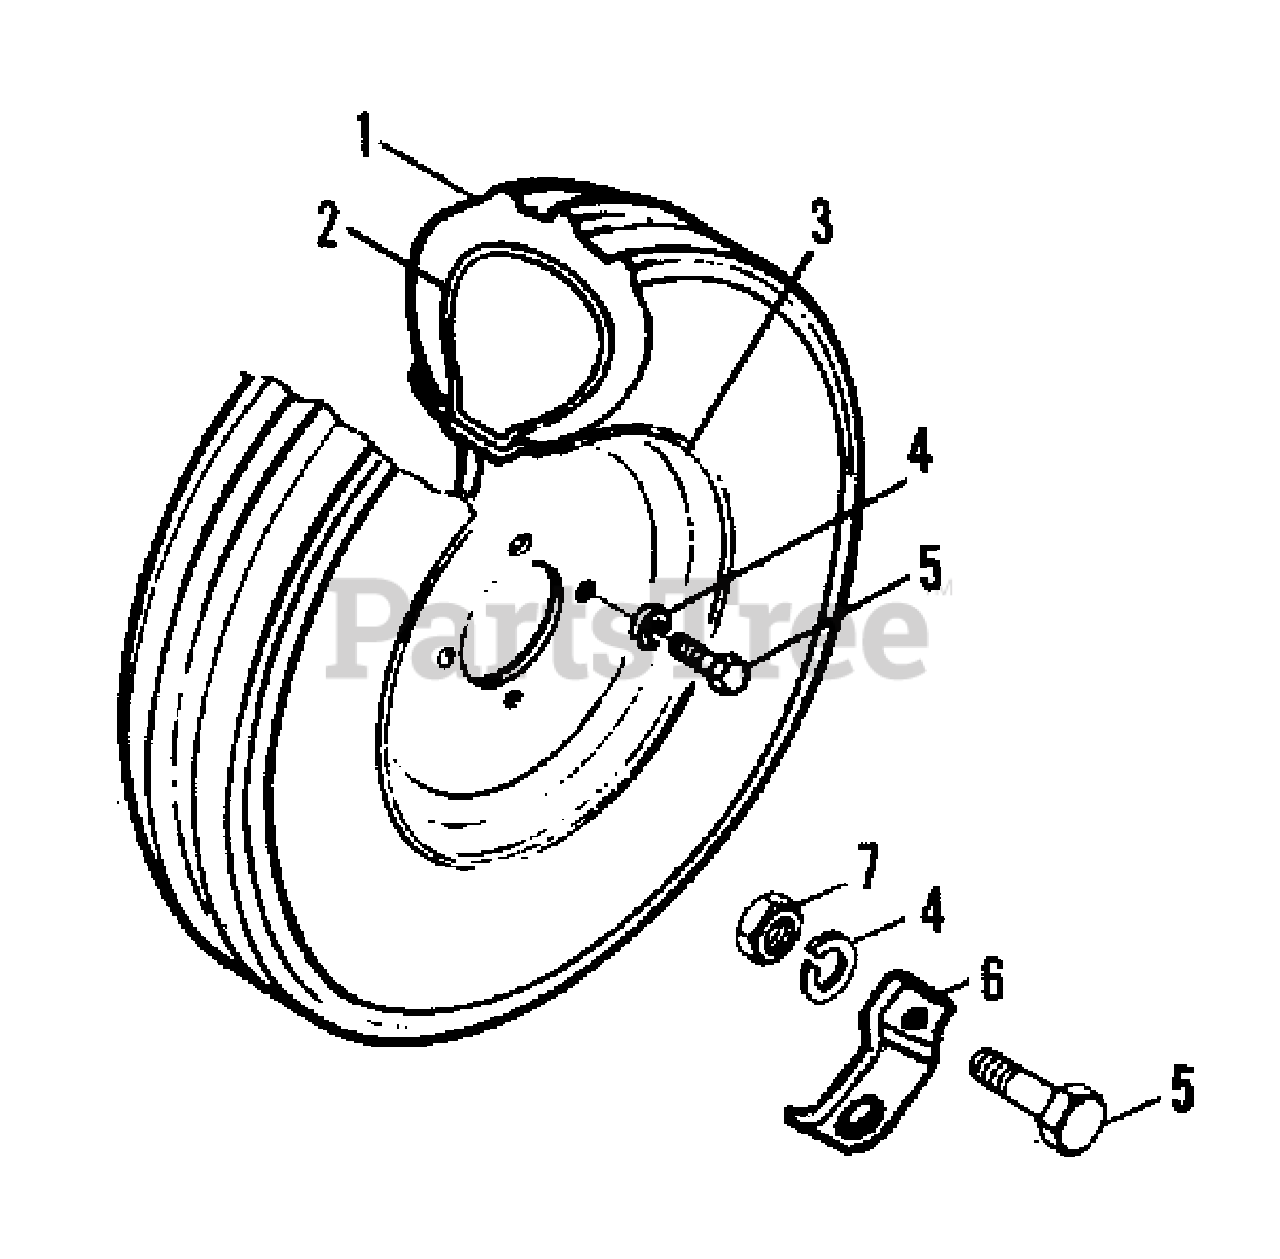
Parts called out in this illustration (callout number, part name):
1	TIRE (Obtain locally)
2	TUBE (Obtain locally)
4	LOCKWASHER, M12
6	PROTECTOR, valve
